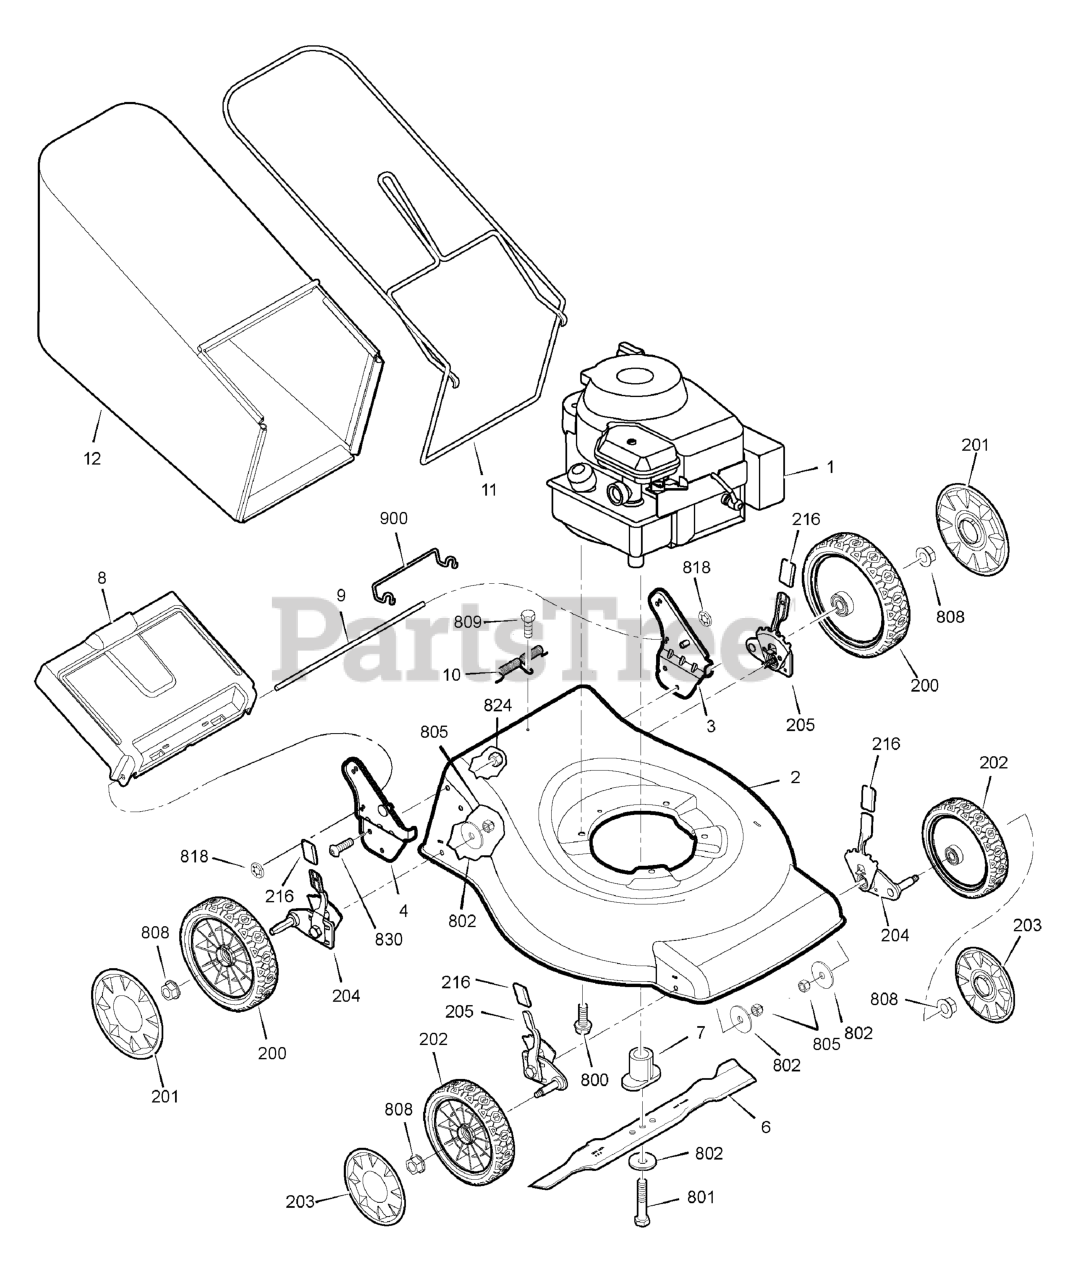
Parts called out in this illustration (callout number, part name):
1	* ENGINE
2	HOUSING ASSEMBLY
3	BRACKET ASSEMBLY, Left Handle
4	BRACKET ASSEMBLY, Right Handle
6	BLADE, 16 in
7	BLADE ADAPTER ASSEMBLY
8	DOOR, Rear
9	ROD, Rear Door
10	SPRING, Torsion Rear Door
11	FRAME ASSEMBLY
12	BAG ASSEMBLY
200	WHEEL, Rear
201	HUBCAP, Rear
202	WHEEL, Front
203	HUBCAP, Front
204	HEIGHT ADJUSTER ASSEMBLY, Left
205	HEIGHT ADJUSTER ASSEMBLY, Right
216	GRIP, Height Adjustment
800	SCREW, Hex Head, 3/8-16 x 1
801	BOLT, Blade, 3/8-24 x 2
802	WASHER, Belleville
805	NUT, Nylock, M8 x 1-1/4
808	NUT, Flange, 3/8-16
809	SCREW, Self Tap, #10-16 x 1/2
818	NUT, Speed
824	Nut, Flange, 5/16-18
830	SCREW , 5/16-18 x 3/4
900	SPRING CLIP, Rear Door
1000	DECAL KIT
1001	MANUAL KIT
